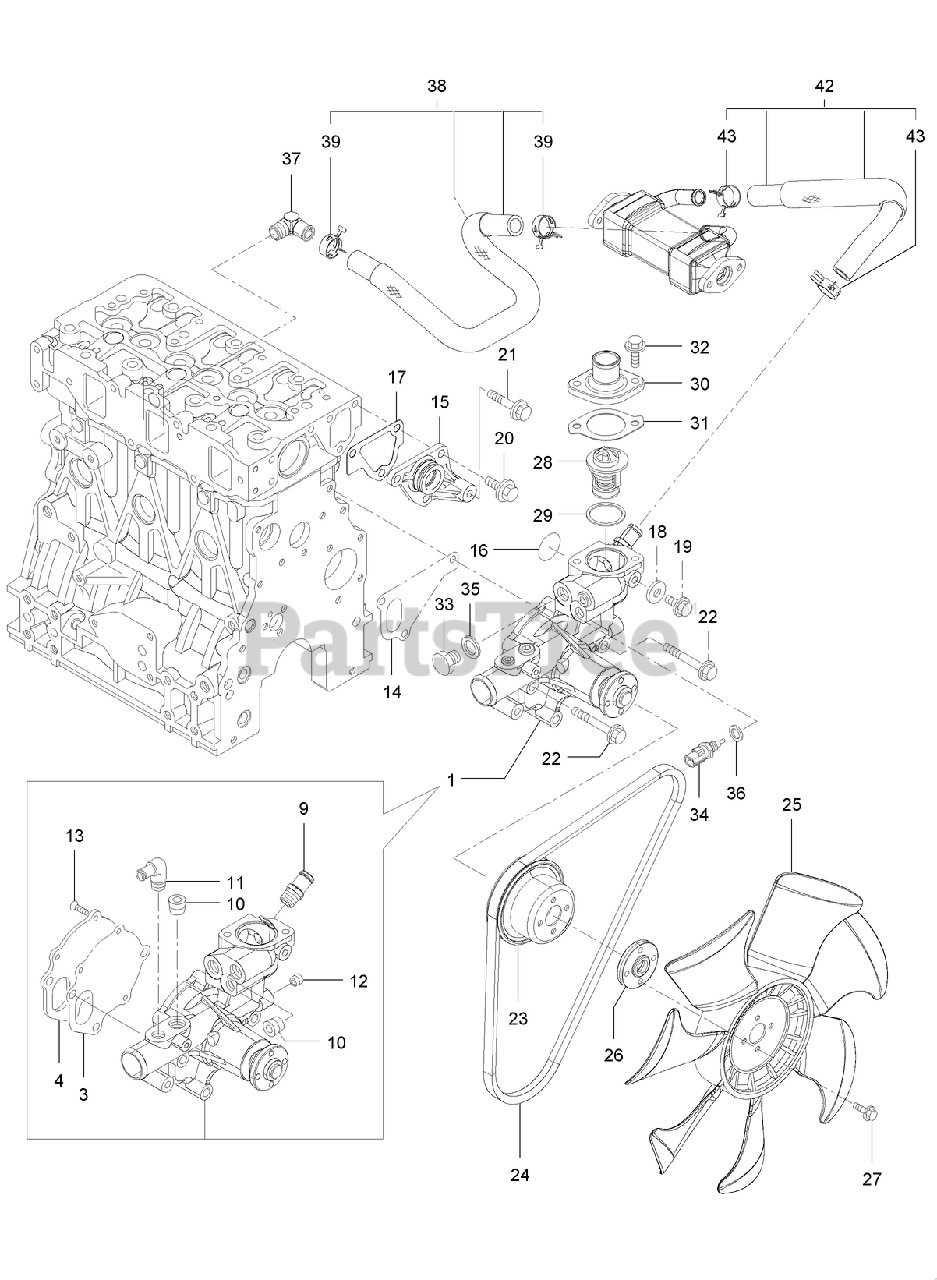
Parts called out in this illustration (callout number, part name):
1	WATER PUMP ASM
3	GASKET
14	GASKET
16	O-RING
17	GASKET
18	GASKET
20	BOLT
23	V-PULLEY
24	V-BELT
26	SPACER
28	THERMOSTAT
29	GASKET
31	GASKET
34	SENSOR-THERMOSTAT, CW
35	GASKET
36	WASHER-SEAL
38	E G R-C PIPE ASM
39	CLIP-HOSE
42	CW PIPE ASM
43	CLIP-HOSE
